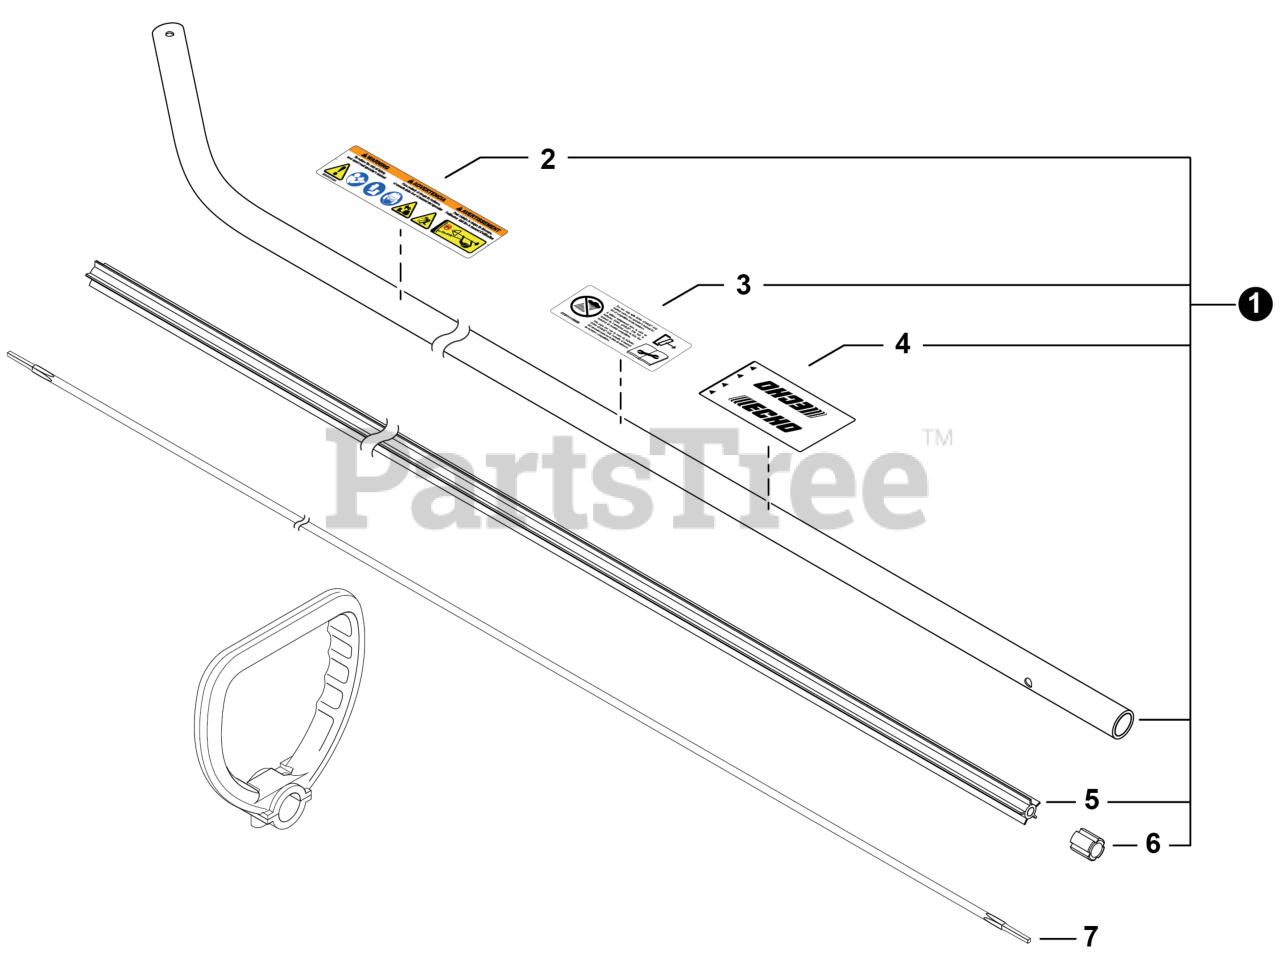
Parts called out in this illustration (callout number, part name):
1	MAIN PIPE ASSY
2	LABEL - CAUTION ISO
3	LABEL - CAUTION - UL
4	LABEL - HANDLE LOCATION
5	LINER, FLEXIBLE 21.6x1420
7	DRIVESHAFT - FLEXIBLE
